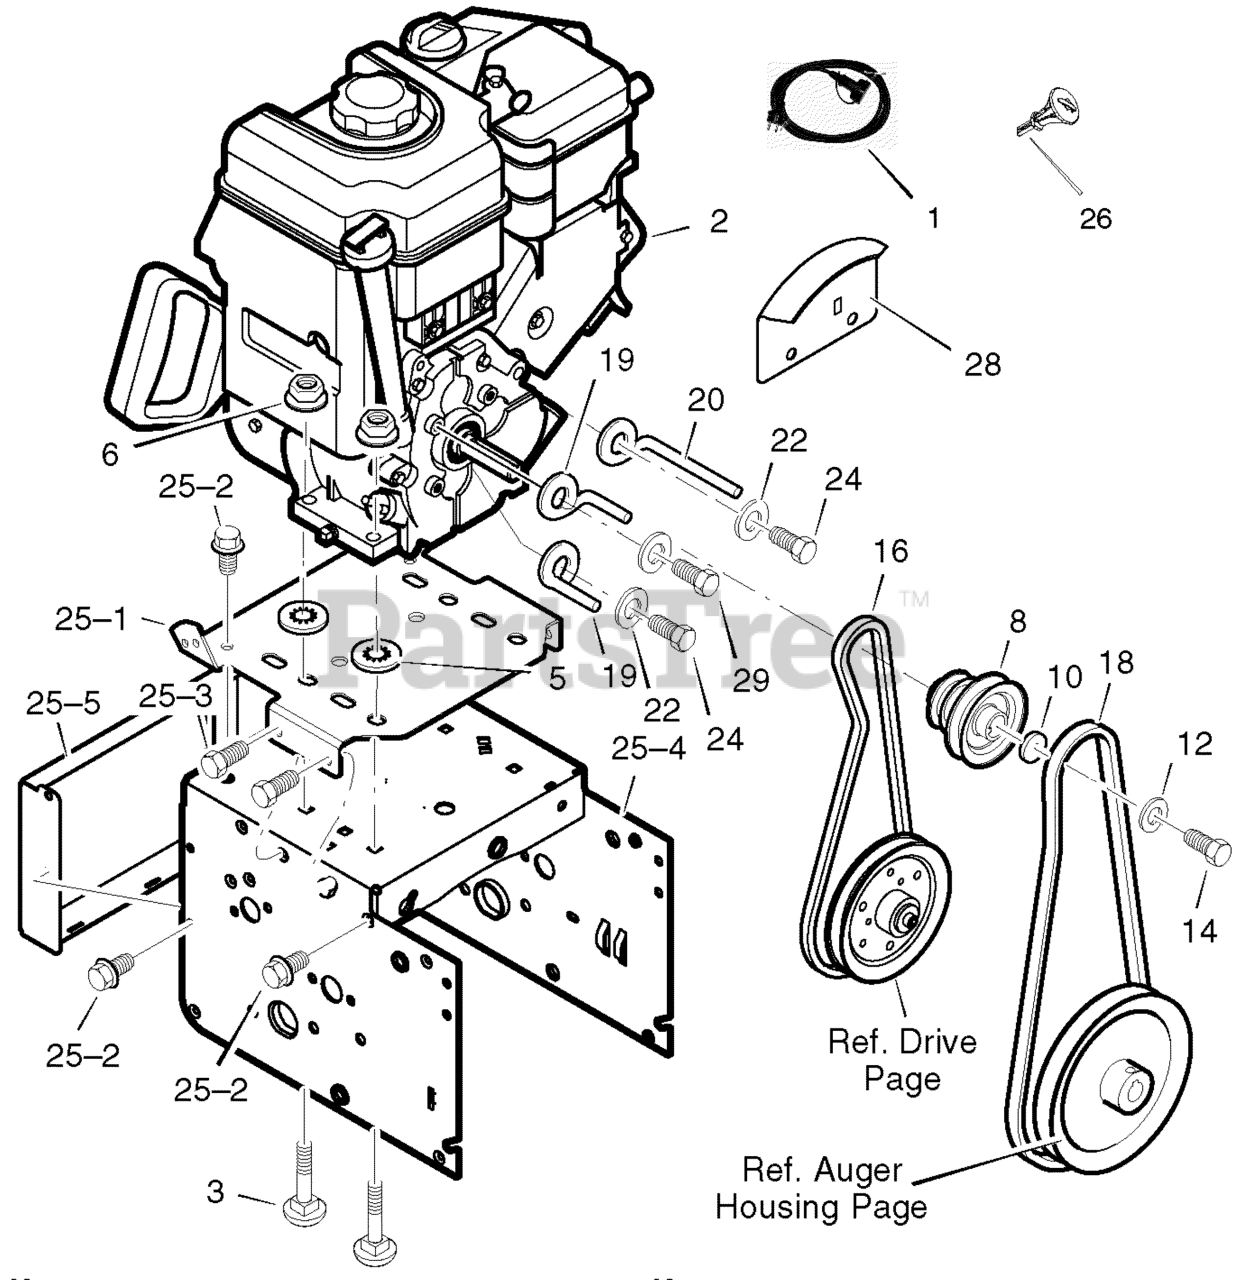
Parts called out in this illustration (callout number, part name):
1	CORD, STARTER
2	ENGINE
3	BOLT, CARRIAGE
5	RETAINER, PUSH
6	NUT, HEX 5/16-18
8	PULLEY, ENGINE
10	WASHER
12	WASHER .38ID
14	SCREW
16	BELT, HYDRO DR
18	BELT, V 4L
19	GUIDE, BELT
20	GUIDE, BELT
22	WASHER
25	FRAME ASSEMBLY
25-1	PLATE, ENGINE
25-2	SCREW, TAP
25-3	SCREW, TAP
25-4	FRAME, MOTORBOX
25-5	PANEL, BACK - HY
26	KEY, ENGINE
28	BRACKET, SHIELD
